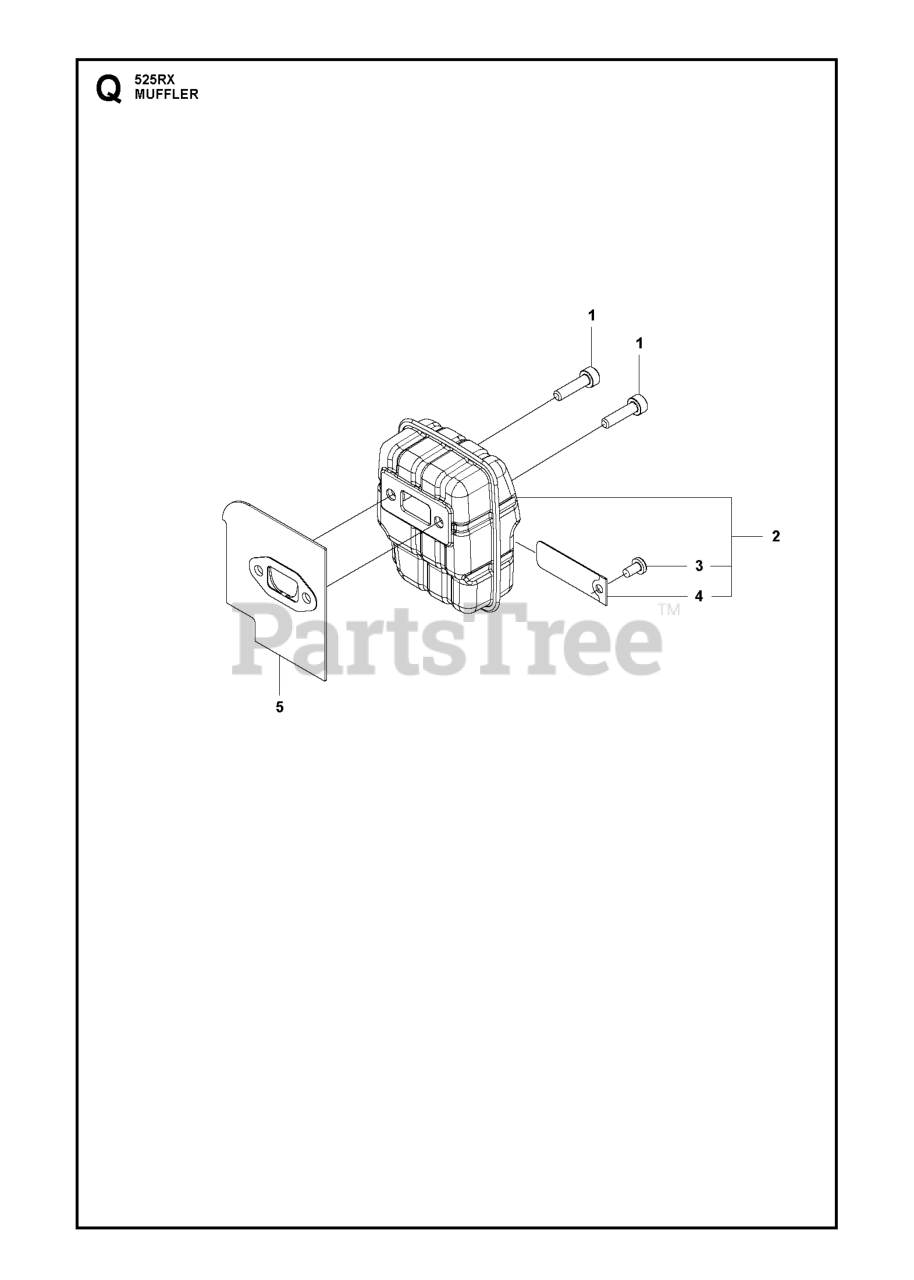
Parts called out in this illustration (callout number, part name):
1	BOLT
2	Mufflers
2	MUFFLER ASSY
3	SCREW CRPANT TYPE F ST4.2X9.5
4	SPARK ARRESTER
5	GASKET MUFFLER
